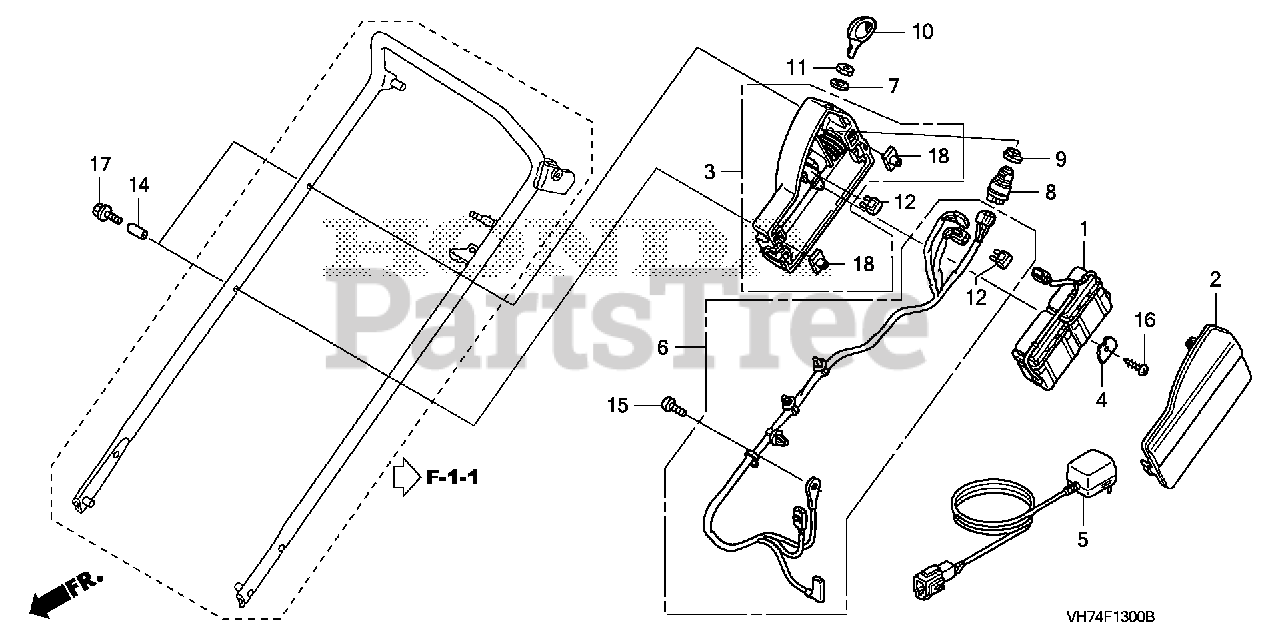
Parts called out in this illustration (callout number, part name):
1	BATTERY ASSY. (12V 2.5AH) (MSDS)
2	COVER ASSY., BATTERY
3	BOX, BATTERY
4	PLATE, BATTERY
5	CHARGER ASSY., BATTERY
6	HARNESS ASSY., MAIN
7	COLLAR, FR. TURN SIGNAL
8	SWITCH ASSY., COMBINATION
9	BASE, COMBINATION SWITCH
10	KEY, COMBINATION SWITCH
11	NUT, SWITCH
12	FUSE A (40A)
14	COLLAR, BATTERY MOUNTING
15	SCREW, PAN (5X8)
16	SCREW, TAPPING (5X12) (PO)
17	BOLT, FLANGE (6X35)
18	NUT, SPECIAL (6X7)
